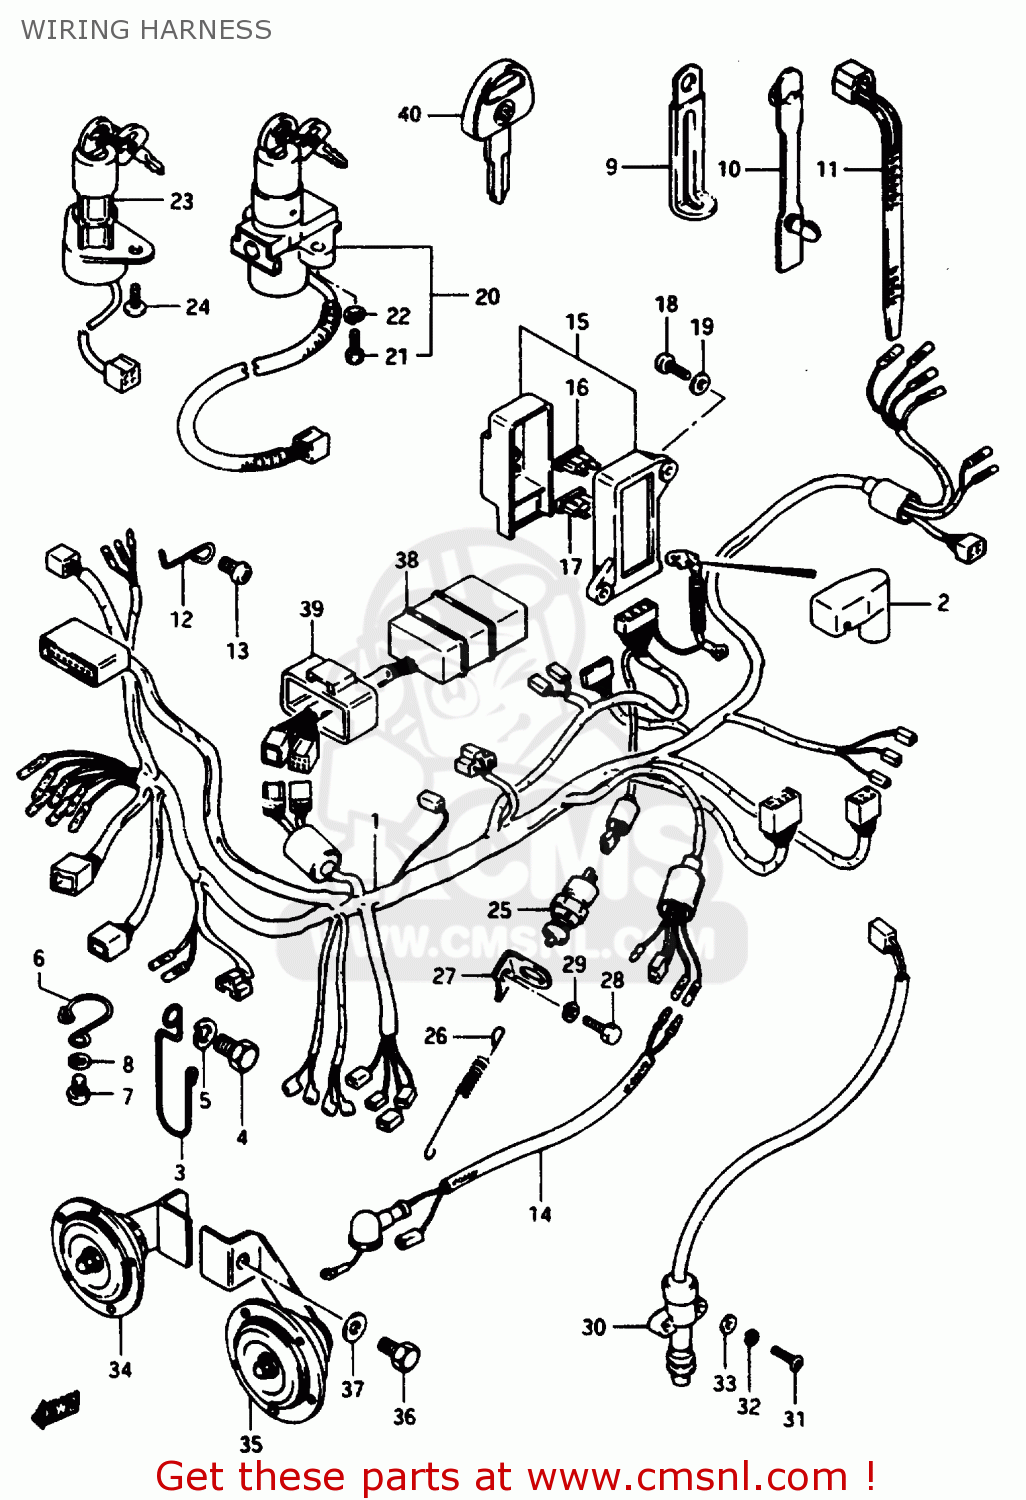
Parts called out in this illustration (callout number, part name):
1	HARNESS,WIRING
2	CAP,BATTERY PLUS
3	GUIDE,WIRING HARNESS
4	BOLT
5	WASHER,LOCK,8.
6	CLIP,WIRING HARNESS
7	SCREW 6X12
8	WASHER
9	CLAMP
10	CLAMP,L:88
11	CLAMP(L:95)
12	GUIDE,WIRING HARNESS
13	SCREW
14	WIRE,OIL TEMPERATURE GAUGE
15	BOX ASSEMBLY,FUSE
16	FUSE(10A)
17	FUSE(15A)
18	SCREW
19	WASHER
20	IGNITION SWITCH/STEERING LOCK
21	BOLT
22	WASHER,LOCK
23	SWITCH ASSY,IGNITION
24	SCREW 6X12
25	SWITCH ASSEMBLY,STOP LAMP
26	SPRING
27	BRACKET,BRAKE LAMP SWITCH
28	BOLT
29	WASHER,LOCK
30	SWITCH ASSY,SIDE STAND WARNING
31	SCREW 5X20
32	WASHER,LOCK
33	WASHER,5MM
34	HORN ASSY, HIGH PITCHED
35	HORN ASSY, LOW PITCHED
36	BOLT
37	WASHER
38	RELAY,LAMP OUTAGE WARNING
39	STAY,LAMP OUTAGE WARNING
40	KEY,BLANK
